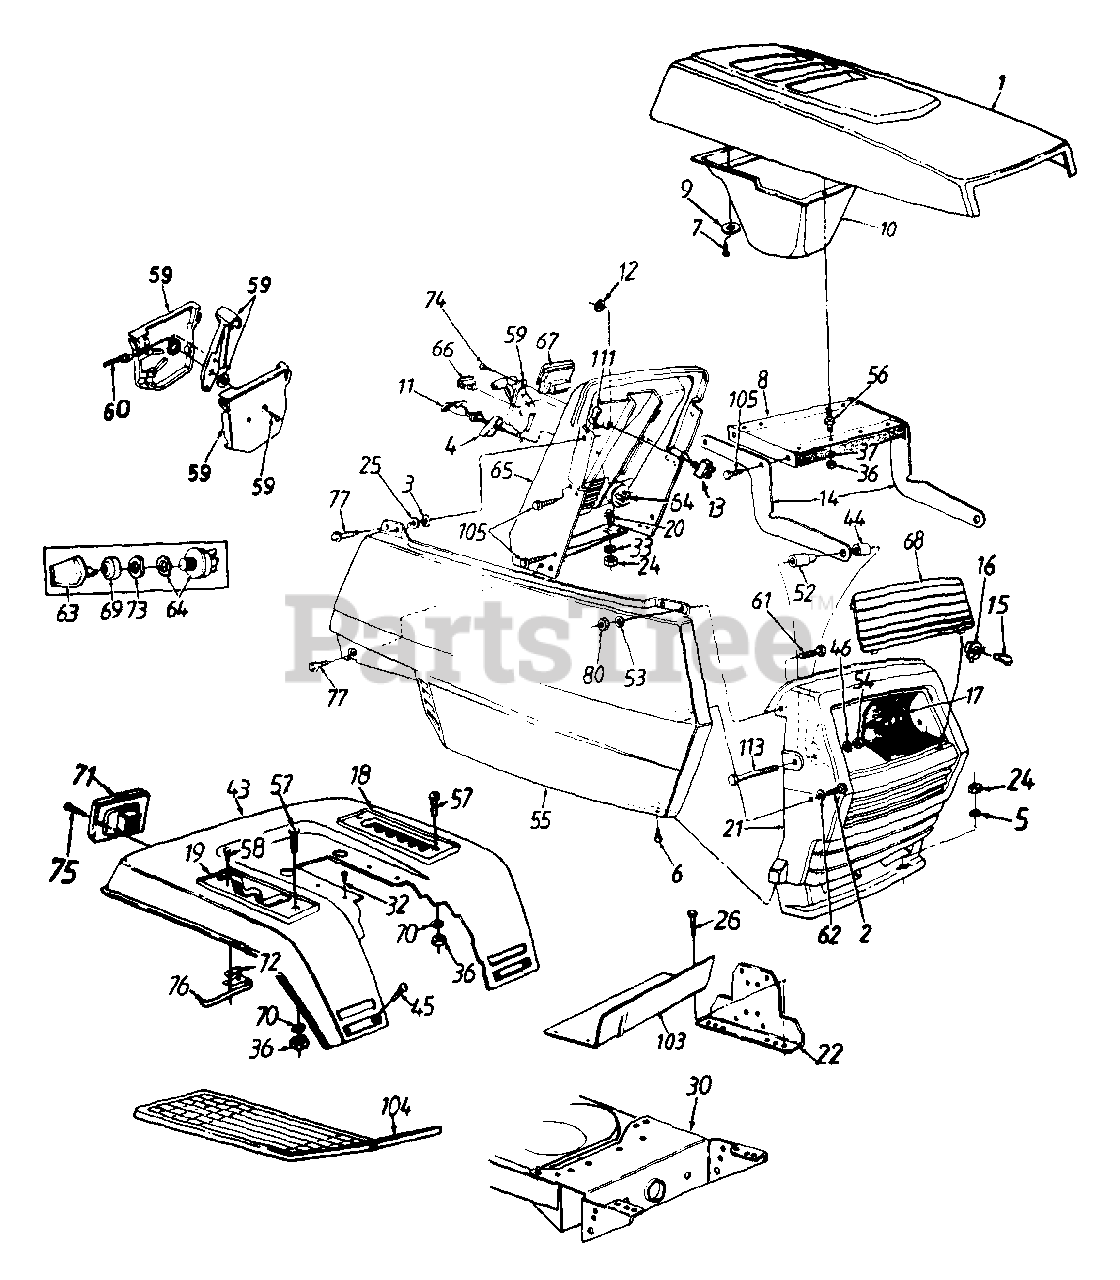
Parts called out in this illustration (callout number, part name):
1	Hood
2	Hex Wash. B-Tap Scr. 1/4 x .62" Lg.
3	Bolt Retainer 1/4" I.D.
4	Retainer Clip
5	Fl-Wash. .34" I.D. x 1"
6	Truss Mach. B-Tap Scr. #10 x .5" Lg.
7	Hex Wash. Hd. AB-Tap Scr. #8 x .5" Lg.
10	Air Plentum
11	Choke Control
12	Hex Nut 1/2-27 Thd.
13	Toggle Switch
14	Hood Hinge
15	Lamp
16	Twist Lock - Lamp Socket
17	Reflector - Headlight
18	Forward/Reverse Index Brkt.
19	7-Speed Selector Plate
20	Hex Bolt 5/16-18 x .75" Lg.
21	Grille
25	Fl-Wash, 1/4" I.D. x .93" O.D.
26	Hex Wash. Hd. B-Tap Scr. 5/16-18 x .5" Lg.
32	Hex Wash. Hd. AB-Tap Scr. 5/16 x .75" Lg.
33	Bell-Wash. .345" I.D. x .88"
36	Hex Nut 1/4-20 Thd.
37	Bell-Wash. .265" I.D. x .75"
45	Carriage Bolt 1/4-20 x .50" Lg.
46	Fl-Wash. .328" I.D. x .68" O.D.
52	Shld, Spacer .33" I.D.
53	Fl-Wash. .281" I.D. x .5" O.D.
54	Hex Cent. L-Nut 5/16-18 Thd.
55	Side Cover - R.H.
56	Double Ended Stud 1/4-20 Thd.
57	Truss Mach. Scr. 1/4-20 x .75" Lg.
58	Hex Wash Hd. AB-Tap Scr. #8 x .5" Lg.
59	Throttle Control Box Ass'y.
60	Throttle Control Wire 35" lg.
61	Hex Bolt 1/4-20 x .62" Lg.
62	Fl-Wash. .281" I.D. x .73" O.D.
64	Ignition Switch
65	Dash Panel
66	Light Switch
67	Ammeter
68	Lens
69	Ignition Switch Cap
70	L-Wash. 1/4" I.D.
71	Taillight
72	Insulator Nut Plate
73	Ignition Switch Nut
74	Truss Mach. AB-Tap Scr. #10 x .5" Lg.
75	Truss Hd. AB-Tap Scr. #6 x .62" Lg.
76	Reverse Safety Switch
77	Hex Wash. Hd. Tap Scr. 1/4 x .75" Lg.
80	Hex L-Nut 1/4-20 Thd.
105	Hex Tap Scr. 1/4-20 x .5" Lg.
111	Speed Nut 1/4-20 Thd.
113	Hex Bolt 5/16-38 x 2.75"
